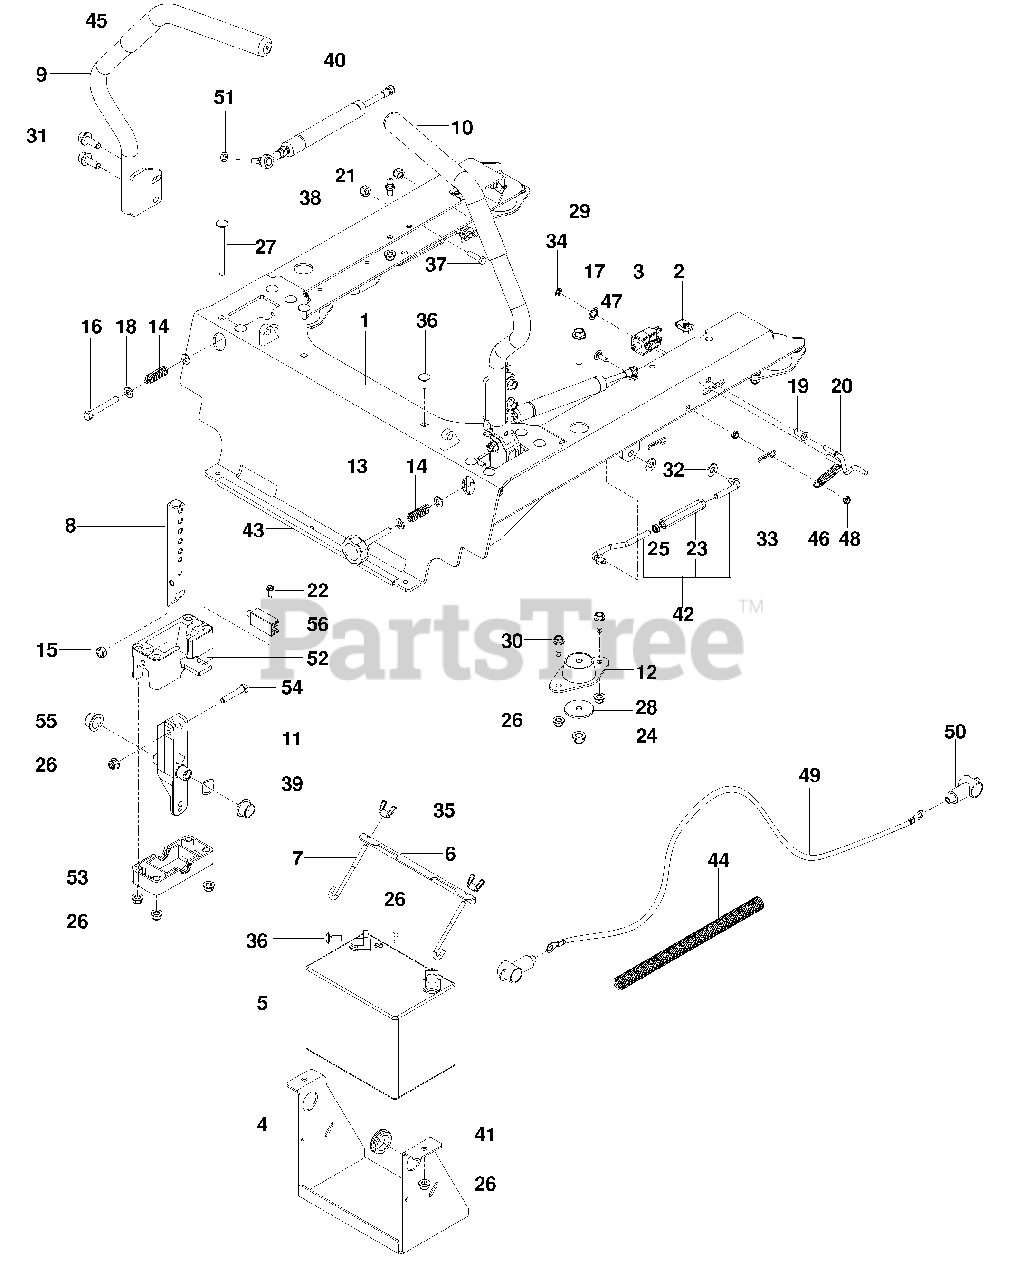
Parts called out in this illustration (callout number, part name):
1	Frame Mount
2	Bolt 7/16-20 X 1 1/2 Hex Nyl
3	Switch, Brake (3-Pole)
4	Bracket, Battery
5	Battery
6	Bracket, Battery Mount
8	Lever, Motion
9	Lever, W/ Grip, Rt
10	Lever, W/ Grip, Lt
11	Lever, Control
12	Mount, Iso
15	Nut 5/16-18 Hex
16	Bolt 5/16-18 X 2 1/2 Hex Tpblt
17	Retainer Nut 3/8
18	Washer 5/16 Sae Flat
19	Bushing, 1/4 Flange
20	Link, Switch
21	Ball Stud 10Mm
22	Screw 10-24 X 5/8 Wsh Hd
23	Turnbuckle 3/8
24	Nut 3/8-16 Hex Flg Nyloc
25	Nut 3/8-24 Hex Jam
26	Nut 5/16-18 Hex Flg Nyloc
27	Bolt 5/16-18 X 3 3/4 Rd Hd
28	Washer 3/8 Special
29	Screw 3/8-16 X 2 Hex Flg
30	Screw 5/16-18 X 3/4 Hex Flg
31	Screw 3/8-16 X 1 Hex Flg
32	Washer 3/8 Sae Flt
33	Hairpin Cotter
34	Push Nut, 1/4"
35	Wingnut 1/4-20 Nyloc
36	Bolt 5/16-18 X 3/4 Rd Hd
37	Bolt 10-24 X 3/4 Socket Hd
38	Nut 10-24 Hex Nyloc
39	Washer, Wave
40	Dampener Assy
41	Rubber Grommet
42	Seat Strut Assy
43	Flex Trim
44	Loom, Split, 5/8
45	Grip, Lever
46	Spring
47	Bolt 1/4-20 X 3/4 Gr2 Rd Hd
48	Nut 1/4-20 Hex Thin Nyloc
49	Cable, Positive
51	Washer 5/16 Slw
52	Block, Upper
53	Block, Lower
54	Bolt 5/16-18 X 1 3/4 Hex Nyl
55	Bearing, Flange
56	Switch N.C.
